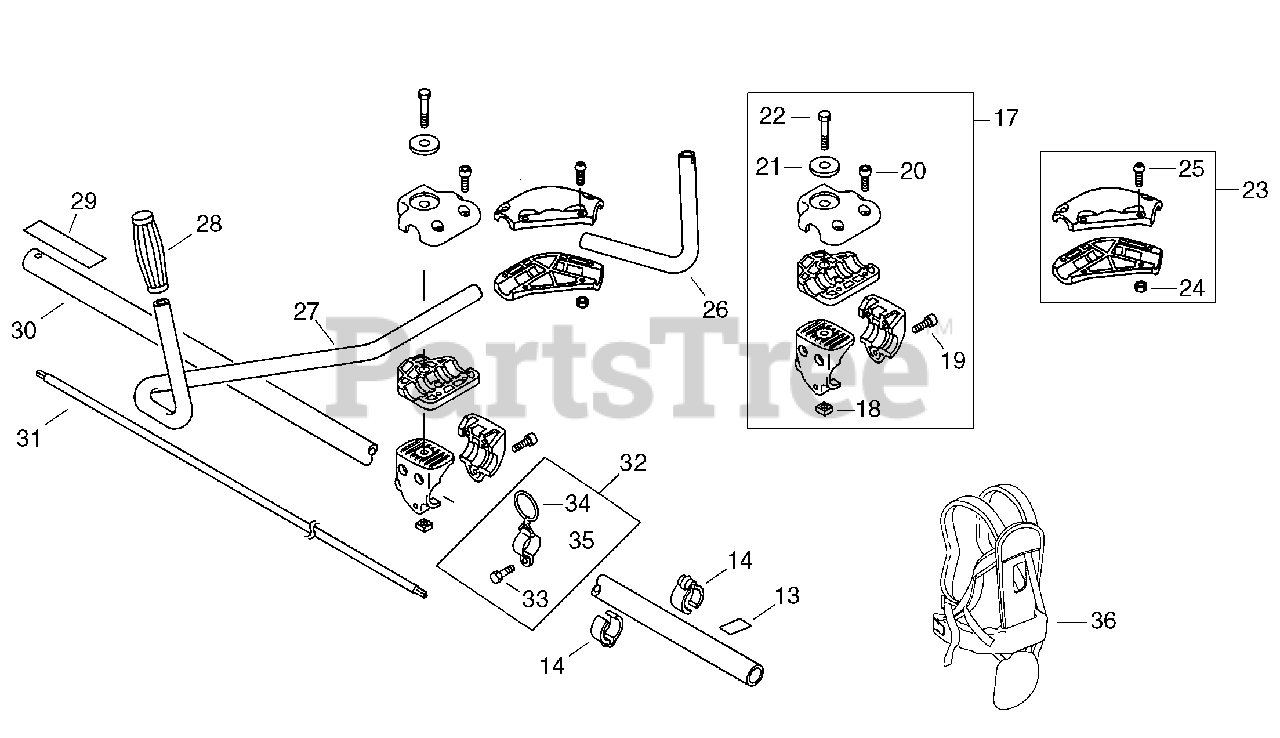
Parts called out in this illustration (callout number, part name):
13	LABEL - ALIGNMENT
17	HANDLE BRACKET KIT
19	SCREW - 5X30
20	SCREW - 5X20
21	WASHER - 8
22	BOLT - 8X55
23	HANDLE BRACKET KIT
25	SCREW - 5X22
26	HANDLE, FRONT - RIGHT
27	HANDLE, FRONT - LEFT
28	GRIP, HANDLE
29	LABEL - CAUTION
30	MAIN PIPE ASSY
31	DRIVESHAFT - SOLID
32	HANGER ASSY
33	SCREW - 5X12
35	CLAMP
36	HARNESS ASSY
